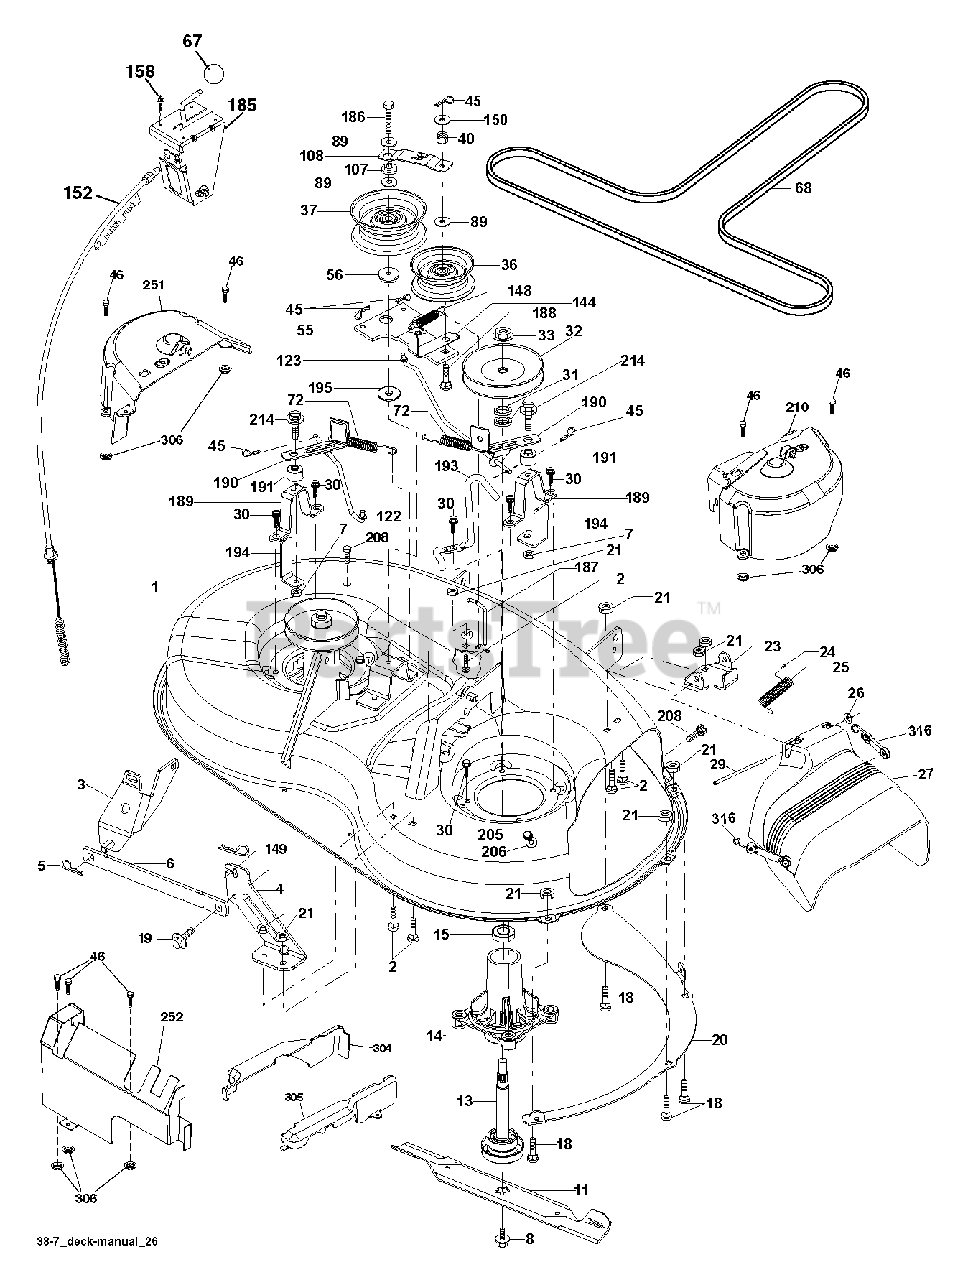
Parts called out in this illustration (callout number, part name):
1	DECK.WELDMENT.38"2005
2	BOLT
3	BRKT ASM SWAY BAR
4	BRACKET DECK SWAY BAR 38"/42"
5	RETAINER-SPRNG RB
6	BAR SWAY DECK
7	NUT.71038.31-18.HEX.NYLOCK
8	BOLT.WASHER.ASM.7/16-2
11	BLADE 38" PREMIUM
13	SHAFT.ASM.MDRL.N/GREASE.38
14	HOUSING MANDREL
18	BOLT
19	BOLT SHD 5/16-18
20	BAFFLE VORTEX
21	LOCKNUT
23	BRKT.DEFLECTOR.38"2005+
24	CAP-SLEEVE LT
25	SPRING.TORSION.DEFLECT
26	NUT PUSH M
29	ROD.HINGE
30	SCREW, WASHER HEAD
31	WASHER.SPACER.MANDREL
32	PULLEY MANDREL
33	NUT.FLANGE.LOCK.TOP
36	FLAT IDLER PULLEY
37	PULLEY.IDLER.FLAT.UNPLATED
40	LOCKNUT
45	RETAINER M
55	IDLER ARM
56	SPACER.RETAINER.MOWER
67	KNOB T (3/8 HOLE)
68	V-BELT.MOWER.38"2005+
72	SPRING.BRAKE.RETURN.38"
89	WASHER
107	SPACER.IDLER.ARM
108	STIFFENER.IDLER.ARM
122	ROD, BRAKE LH LINK
123	LINK.BRAKE.38"RIGHT
144	KEEPER BELT
148	IDLER RETURN SPRING
149	SPRING.RETAINER.YELLOW.ZINC
150	WASHER LT
152	CABLE.CLUTCH.38".SERVICE
158	SCREW
185	HEAD ASM. CABLE CLUTCH
186	SCREW.HXWSH.3/8
187	KEEPER BELT
188	BOLT, CARRIAGE IDLER
189	STAND, BRAKE
190	ARM, BRAKE
191	SPACER, BRAKE
193	KEEPER BELT RH MANDREL
194	GUARD BRAKE
195	WASHER 12/32X2X10GA
205	SCREW
208	SCREW 3/8-16X1/2
214	BOLT/WASHER ASM 5/16-18
306	PALNUT 1/4
